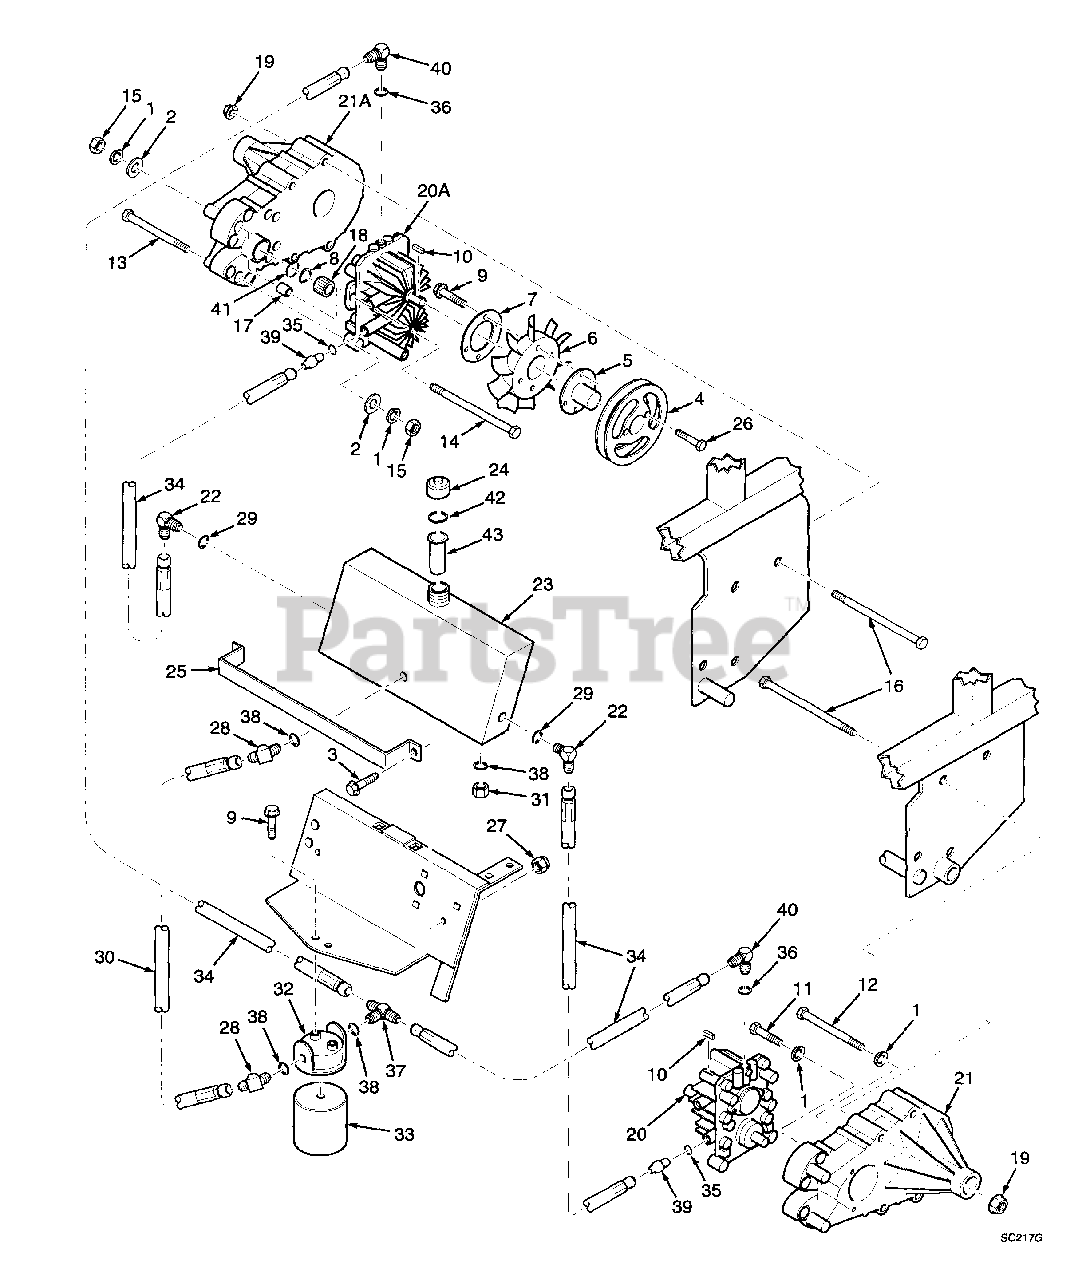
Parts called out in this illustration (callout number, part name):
1	Lockwasher, 5/16"
2	Flatwasher, 5/16" (.344 x .688 x .065)
3	Bolt, Serrated Flange Hex Head 1/4-20 x 3/4"
4	Pump, Pulley
5	Tapered Hub, 15mm Bore
6	Fan
7	Washer, Back-up
8	Snap Ring
9	Bolt, Serrated Flange Hex Head 1/4-20 x 1/2"
10	Key, 5mm x 5mm x 25mm
11	Bolt, Hex Head 5/16-18 x 1-3/4"
12	Bolt, Hex Head 5/16-18 x 4-1/2"
13	Bolt, Hex Head 5/16-18 x 5"
14	Bolt, Hex Head 5/16-18 x 7-1/2"
15	Nut, Hex 5/16-18
16	Bolt, Hex Head 3/8-16 x 4"
17	Spacer
18	Gear
19	Nut, Serrated Flange Hex Head 3/8-16
20	Pump, LH
20A	Pump, RH
21	Axle, LH
21A	Axle, RH
22	Elbow, 90ø 9/16-18 JIC to 9/16-18 "O" Ring
23	Oil Tank Reservoir
24	Cap, Oil Reservoir
25	Strap, Oil Reservoir
26	Bolt, Hex Head 1/4-20 x 1-1/4"
27	Nut, Elastic Stop 1/4-20
28	Elbow, 45 Degree 3/4-16 JIC to 3/4-16 "O" Ring
29	"O" Ring, 5/64 x 15/32 ID
30	Hose Assembly, Filter Inlet
31	Plug, 3/4-16 "O" Ring
32	Head, Oil Filter
33	Oil Filter, Special
34	Hose Assembly
35	"O" Ring, 3/32 x 3/4 ID
36	"O" Ring, 1/16 x 3/8 ID
37	1/2" T-fitting, 3/4-16 JIC to 3/4-16 "O" Ring
38	"O" Ring, 3/32 x 5/8 ID
39	Tube Union 3/4-16 JIC to 7/8-14 "O" Ring
40	Elbow, 90 Degree 9/16-18 JIC to 7/16-20 "O" Ring
41	"O" Ring
42	Gasket, Hydraulic Tank Cap
43	Filler Neck Insert
